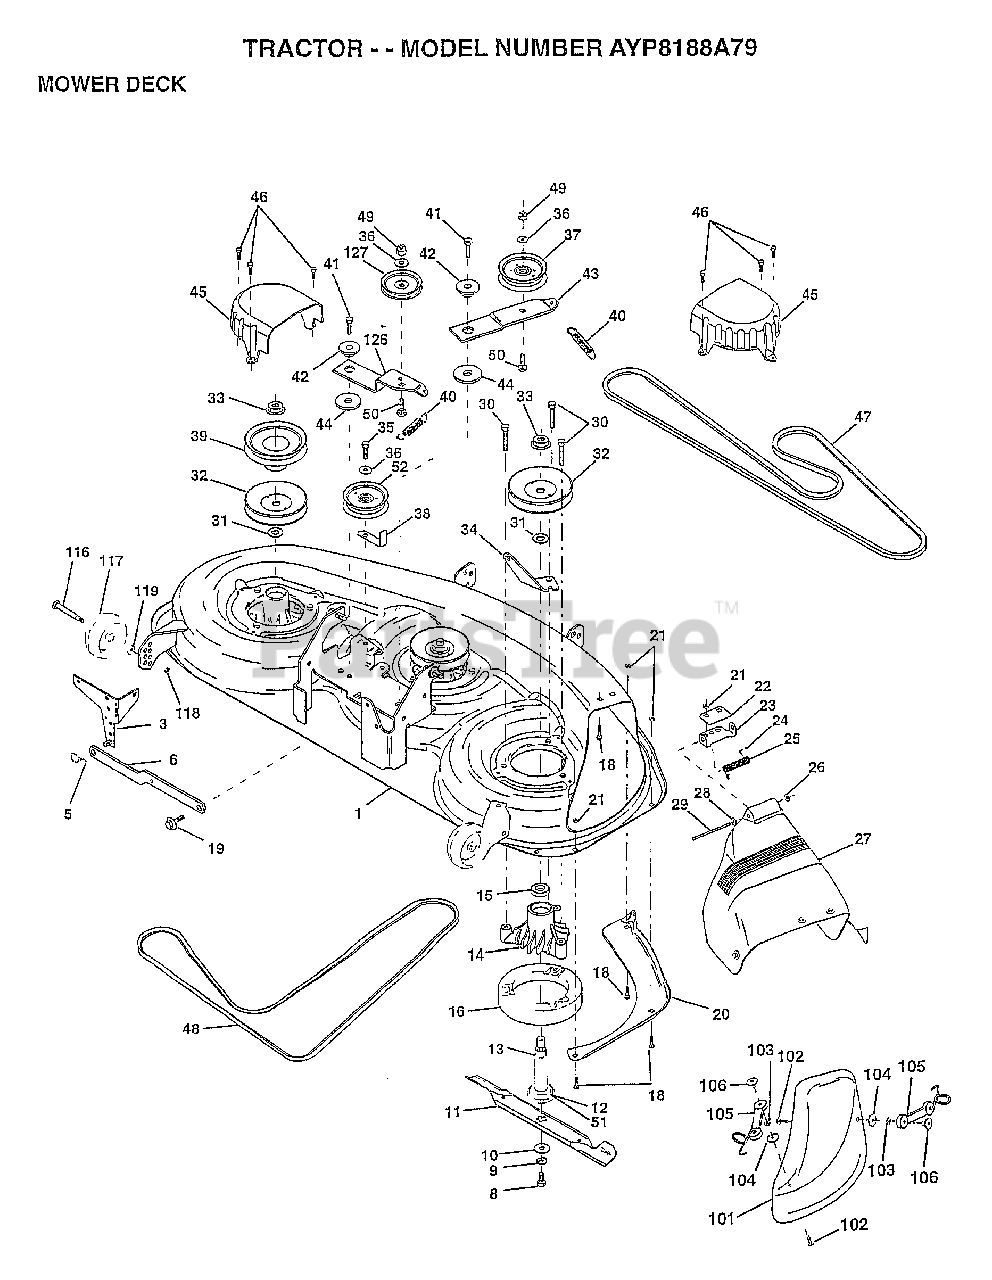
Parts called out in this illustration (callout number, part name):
1	DECK ASM. MOWER 46"
3	BRKT.ASM.SW.44/50
8	BLADE BOLT
10	WASHER.HARD.BLADE
12	BEARING.BALL
13	SHAFT.ASM.W/BRNG
14	HOUSING.MAND.44.V
15	BEARING
16	STRIPPER RND MWR
18	BOLT
19	BOLT SHD 5/16-18
20	BAFFFLE.VORTEX.46
22	STIFFENER BRKT
23	DEFLECTOR BRKT
24	CAP-SLEEVE LT
25	SPRING, TORSION, DEFLECTOR
26	NUT PUSH M
27	SHIELD DEFLECTOR
28	WASHER
29	HINGE ROD
31	WASHER
32	PULLEY.MAND.36/46
34	ANCHOR.SPRING.46
35	SCREW LT
36	WASHER
37	FLAT IDLER PULLEY
38	"KEEPER BELT,IDLER"
39	PULLEY.DRV.DCK.46
40	"SPRING.SEC.44""VEN"
41	SCREW
42	SPACER RETAINER
43	ARM.IDLER.DECK.46
44	HARDENED WASHER
45	COVER.MANDREL.46
46	SCREW.1/4-20X5/8
47	BELT-V.SEC.46.KEL
48	BELT V PRIM 50
50	BOLT.3/8-16X1.50
51	WASHER.FELT.
52	"PULLEY IDLER,FLAT"
101	COVER.MULCHING.
102	SCREW
103	LOCKWASHER
104	WASHER #10
106	WELDNUT
116	BOLT.SHOULDER
117	WHEEL GAGE DONUT
118	LOCKNUT
119	WASHER
126	ARM.IDLER.PRIM.46
127	PULLEY.IDLER.4.25
